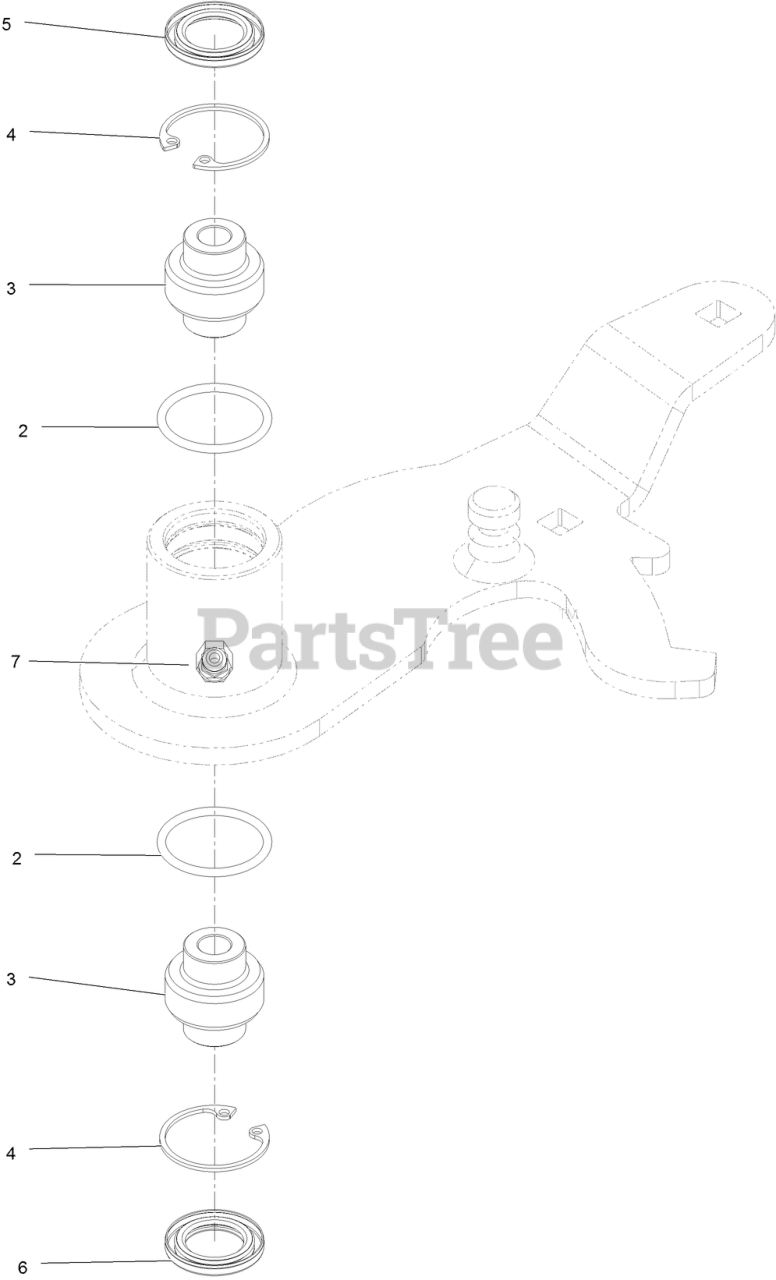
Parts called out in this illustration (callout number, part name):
2	O-RING
3	BEARING-SPHERICAL
4	RING-SNAP
5	SEAL-LIP, SINGLE
6	SEAL-LIP, DOUBLE
7	FITTING-LUBE, 45 DEG
